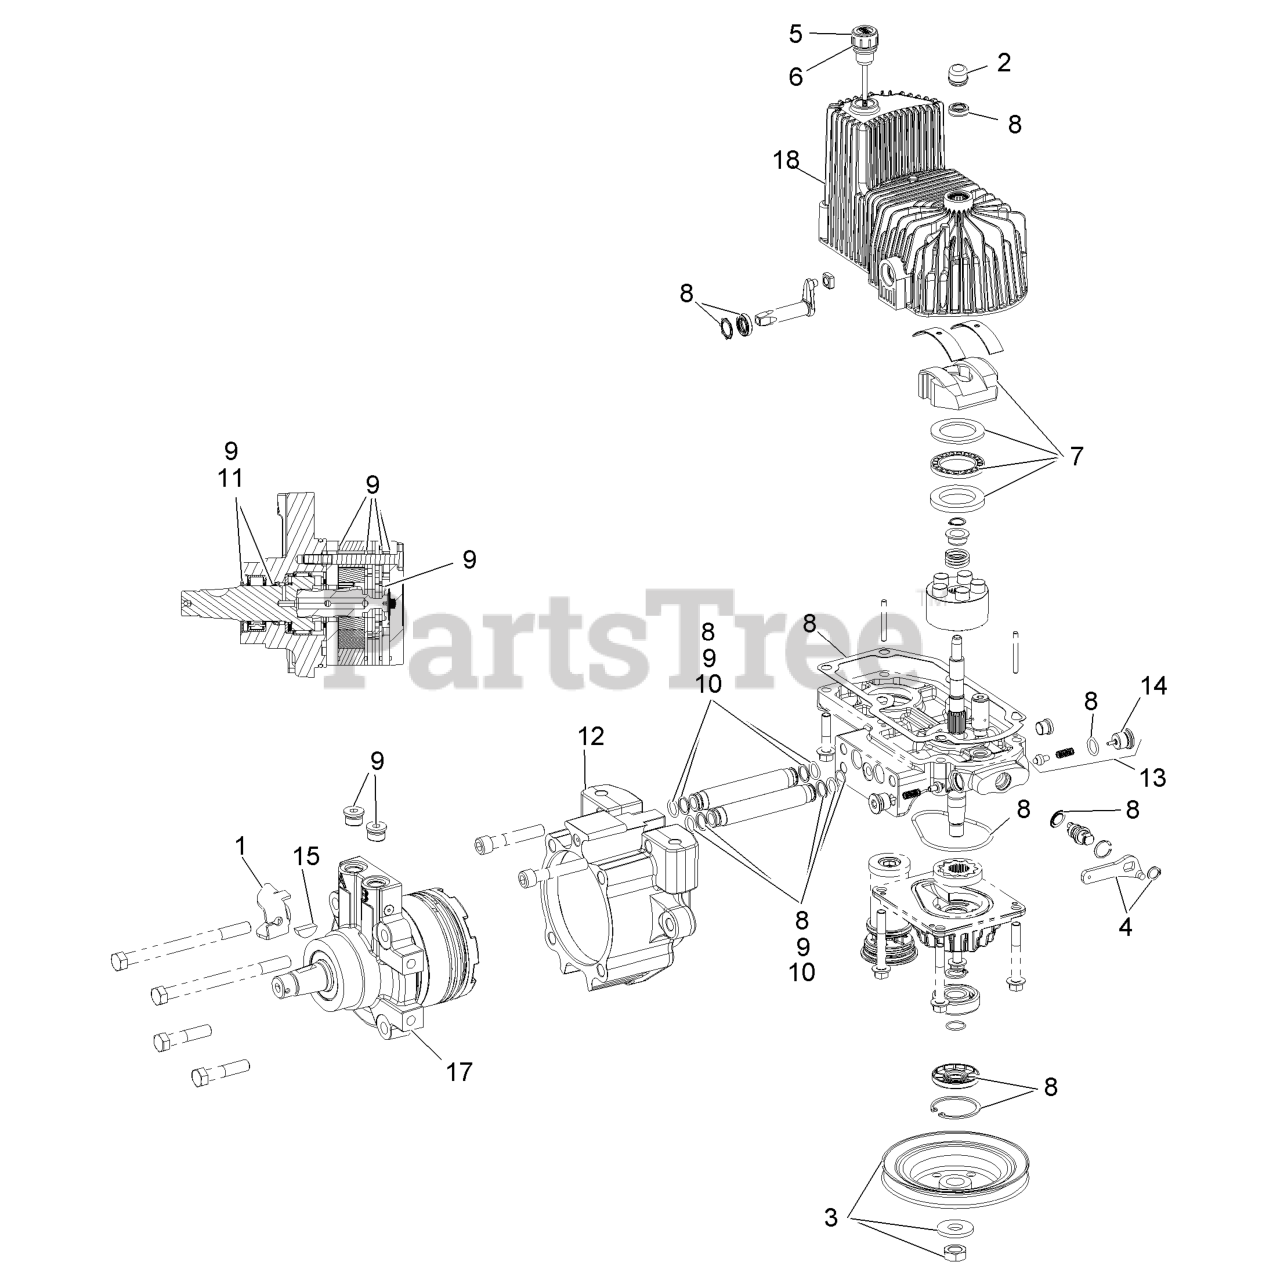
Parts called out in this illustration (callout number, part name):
1	BRACKET-ANCHOR, CABLE
2	COVER-SHAFT, HYDRO
3	PULLEY KIT
4	HANDLE-BYPASS VALVE, HYDRO
5	DIPSTICK-HYDRO W/GASKET
6	GASKET-DIPSTICK, HYDRO
7	SWASH BLOCK KIT
8	PUMP SEAL KIT
9	MOTOR SEAL KIT
10	TUBE SEAL KIT
11	OUTPUT SHAFT SEAL KIT
13	CHECK VALVE ASM
14	PLUG-CHECK (W/O-RING)
15	KEY-WOODRUFF
18	HOUSING-HYDRO, LH
